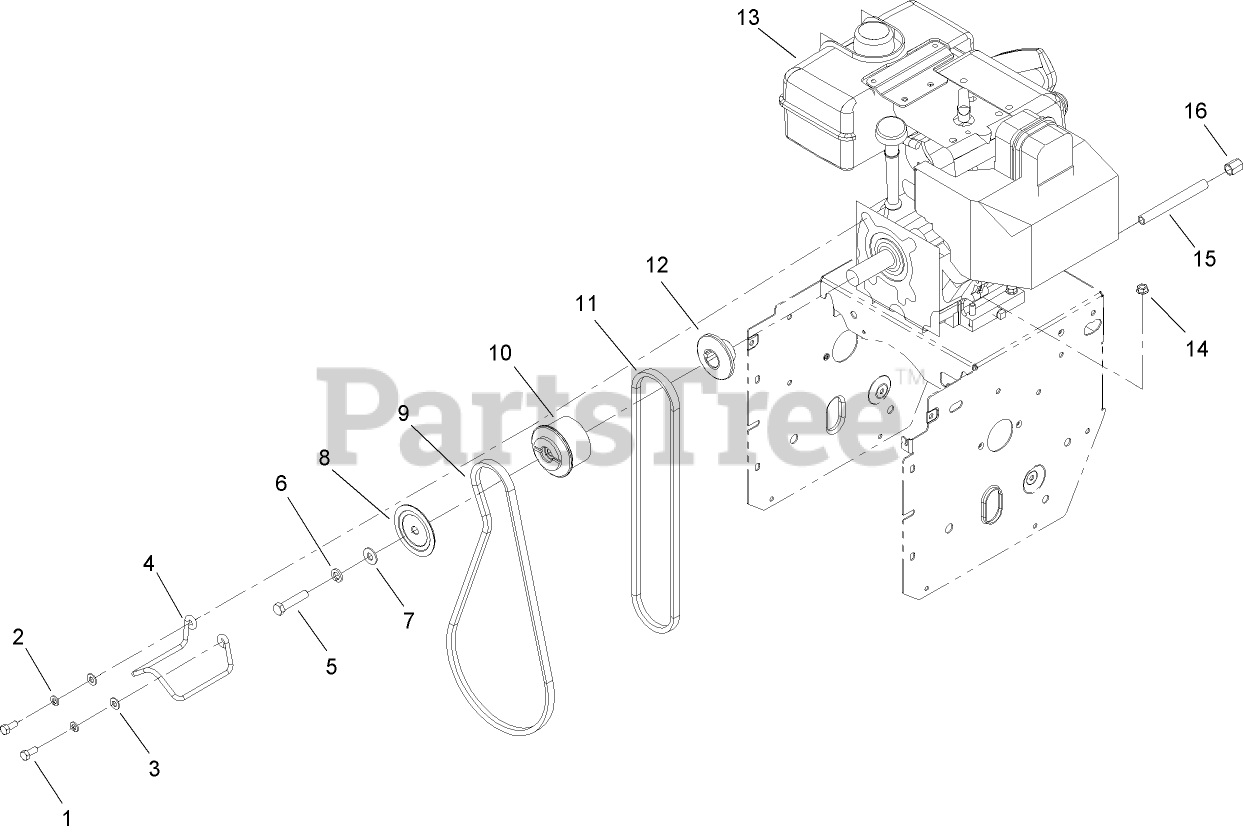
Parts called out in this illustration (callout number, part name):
1	SCREW-HH
2	WASHER-LOCK
3	WASHER-PLAIN
5	SCREW-HH
6	WASHER-LOCK
7	WASHER-FLAT
8	SHEAVE-HALF, IMPELLER
9	BELT-V
10	PULLEY-ENGINE, CENTER
11	V BELT-TRACTION
12	SHEAVE-HALF, TRACTION
13	Loose Parts Package
14	NUT-HF
15	NIPPLE-PIPE
16	CAP-PIPE
